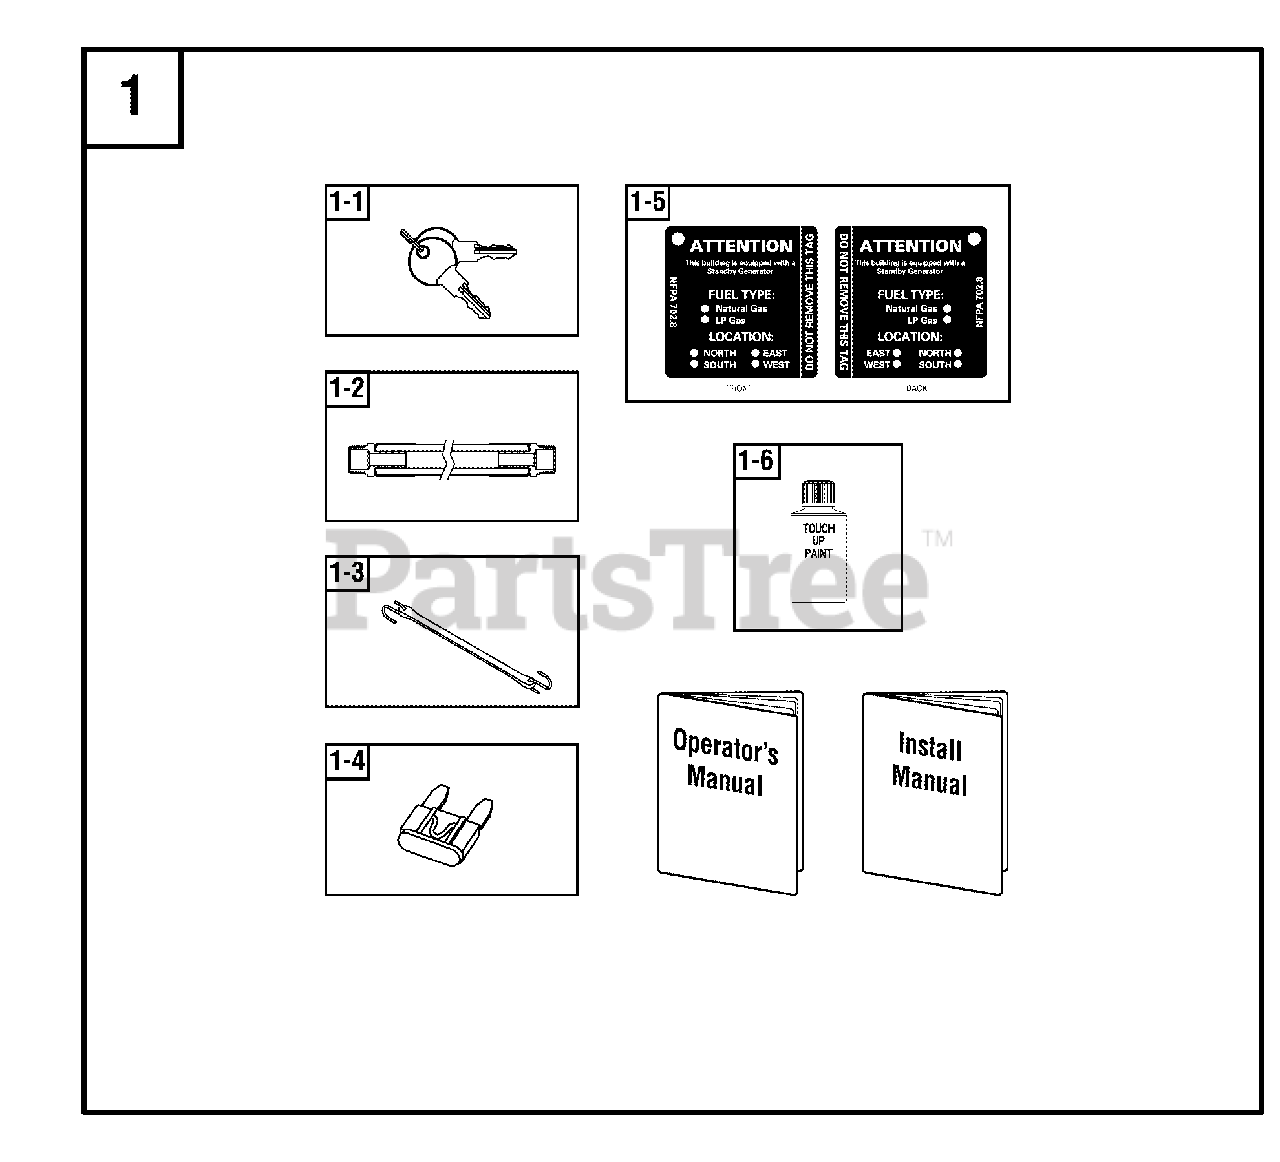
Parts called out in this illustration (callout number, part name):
1	KIT-MANUAL ACC
1-3	STRAP-BATTERY TIEDOWN
1-5	HANG TAG, Attn Standby Equipment
1-6	PAINT- TOUCH-UP, CONT CHAR. TEXTURE
